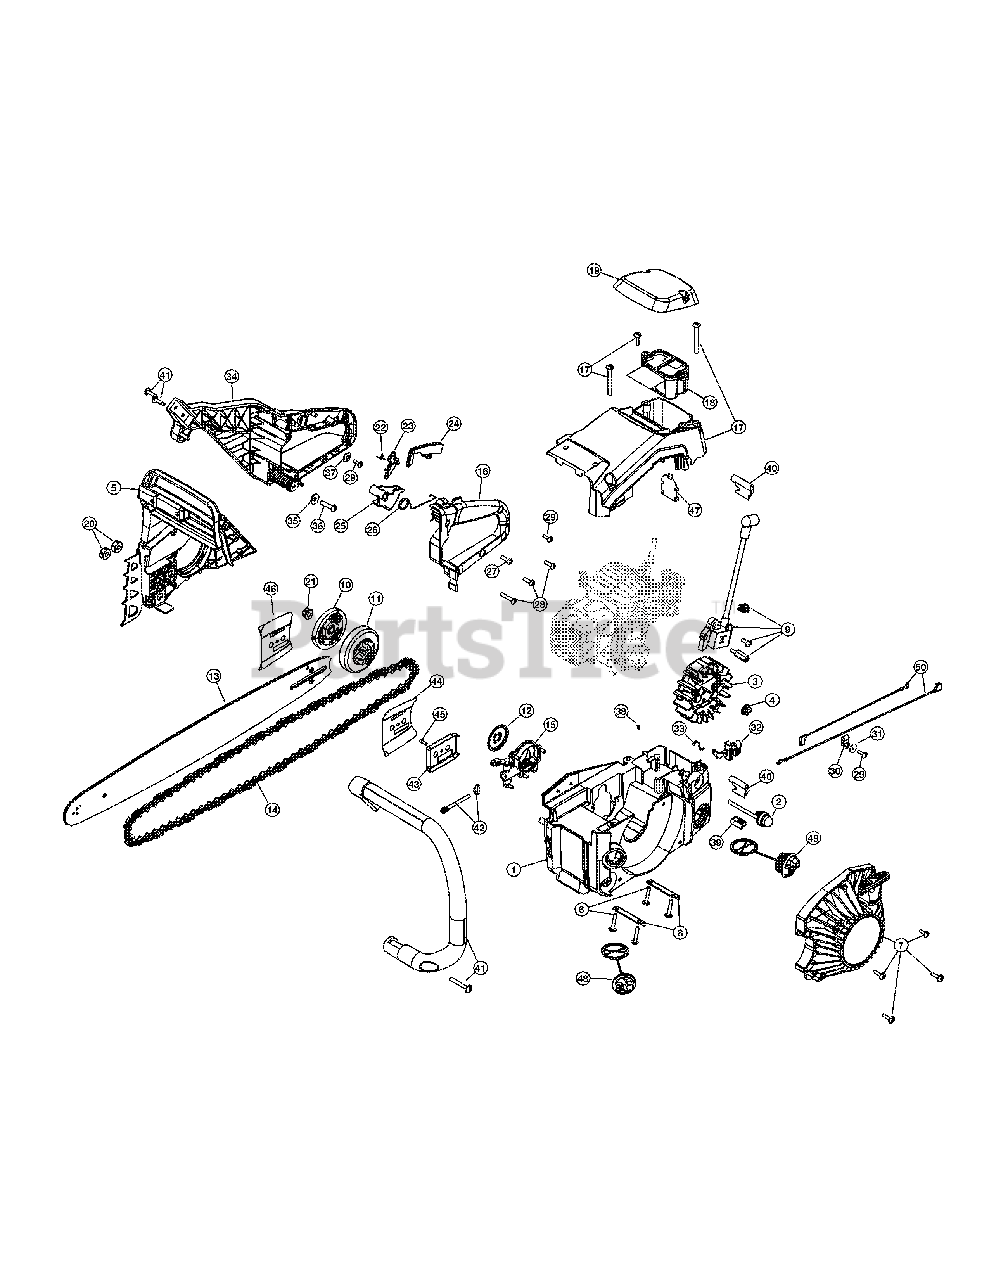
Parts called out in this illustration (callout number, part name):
1	Housing Assembly
2	Primer Bulb Assembly
3	Flywheel Assembly
4	Flywheel Nut
5	Chain Brake Assembly
6	Engine Mount Screw
7	Starter Housing Assembly
8	Engine Mount Plate Assembly (Incl.Ref No. 6)
9	Module Assembly
11	Clutch Drum Assembly
12	Oil Pump Shield
13	Bar
14	18" Chain
15	Oil Pump Assembly
16	Rear Handle Cover Assembly w/switch
17	Top Cover Assembly
18	Air Cleaner Assembly
19	Air Cleaner Cover Assembly
21	Clutch Nut
22	Idle Latch Spring
23	High Idle Latch
24	Trigger Release
25	Throttle Trigger
26	Trigger Release Spring
27	Upper Grip Screw
28	Lower Grip Screw
29	Throttle Clamp Screw
30	Cable Clamp
32	Choke Lever Assembly
34	Rear Handle Assembly
35	Grip Anti-vibration Washer
36	Grip Anti-vibration Screw
37	Throttle Clamp Washer
41	Handle Assembly
42	Tension Screw & Nut Assembly
44	Inner Guide Plate
45	Guide Plate Screw
46	Outer Guide Plate
50	Ground Wire
